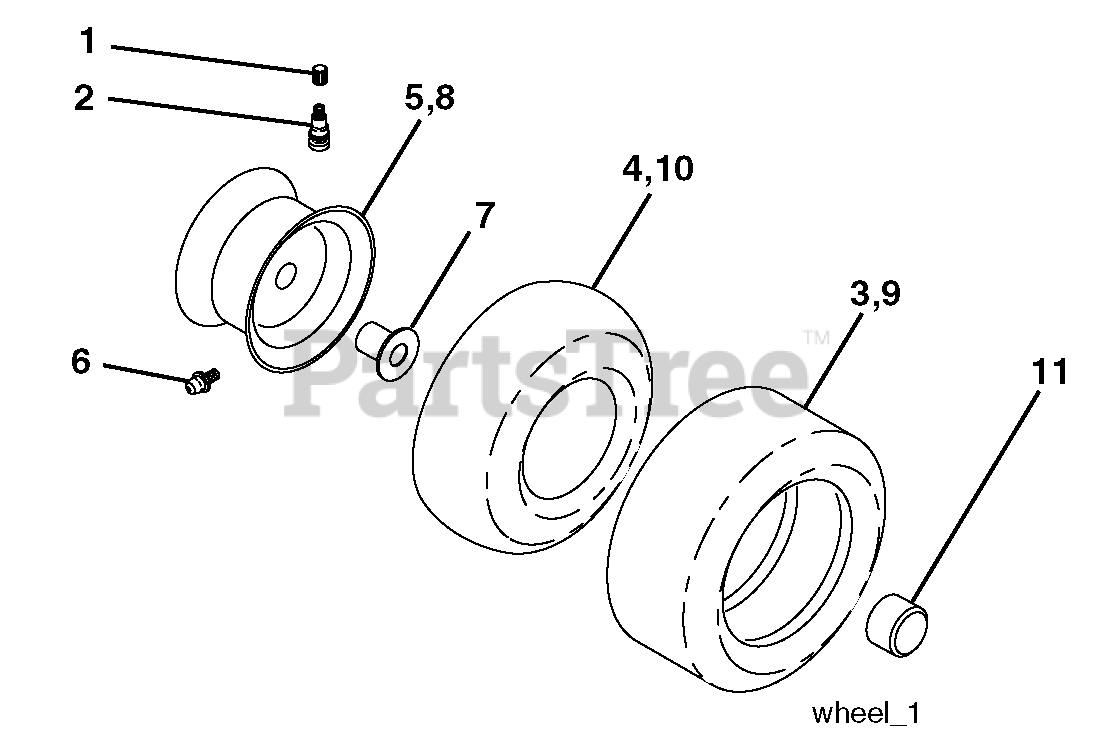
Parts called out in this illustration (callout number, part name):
1	Cap, Tire valve
2	Stem, Valve
3	Tire, Front
4	Tube, Front
5	Rim Assembly, 6" Front
6	Fitting, Grease
7	Bearing, Flange
8	Rim Assembly, 8" Rear
9	Tire, Rear 18 x 9.5-8 Turf Saver
9	Tire, Rear 18 x 9.5-8 Turf Saver LT
10	Tube, Rear
11	Cap, Hub Axle
11	Sealant, Tire (10 oz. Tube)
